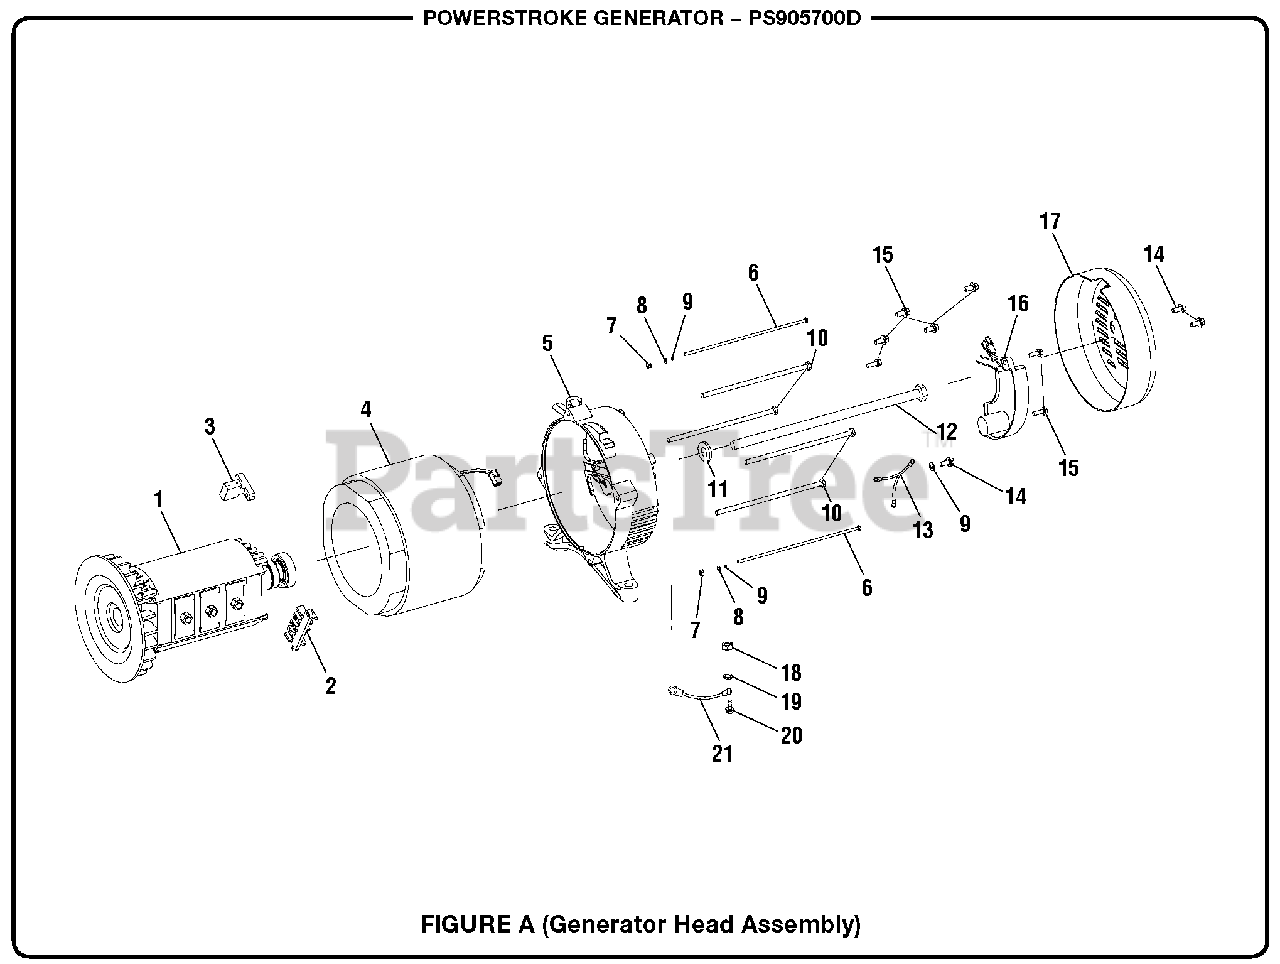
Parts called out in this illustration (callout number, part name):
1	Rotor
3	Grounding Post
6	Bolt (M5 x 158 mm)
8	Flat Washer
9	Spring Washer
12	Rotor Bolt
13	Grounding Wire
14	Bolt (M5 x 12 mm, Hex Flange Hd.)
15	Bolt (M5 x 16 mm, Hex Flange Hd.)
16	Automatic Voltage Regulator
18	Lock Nut
